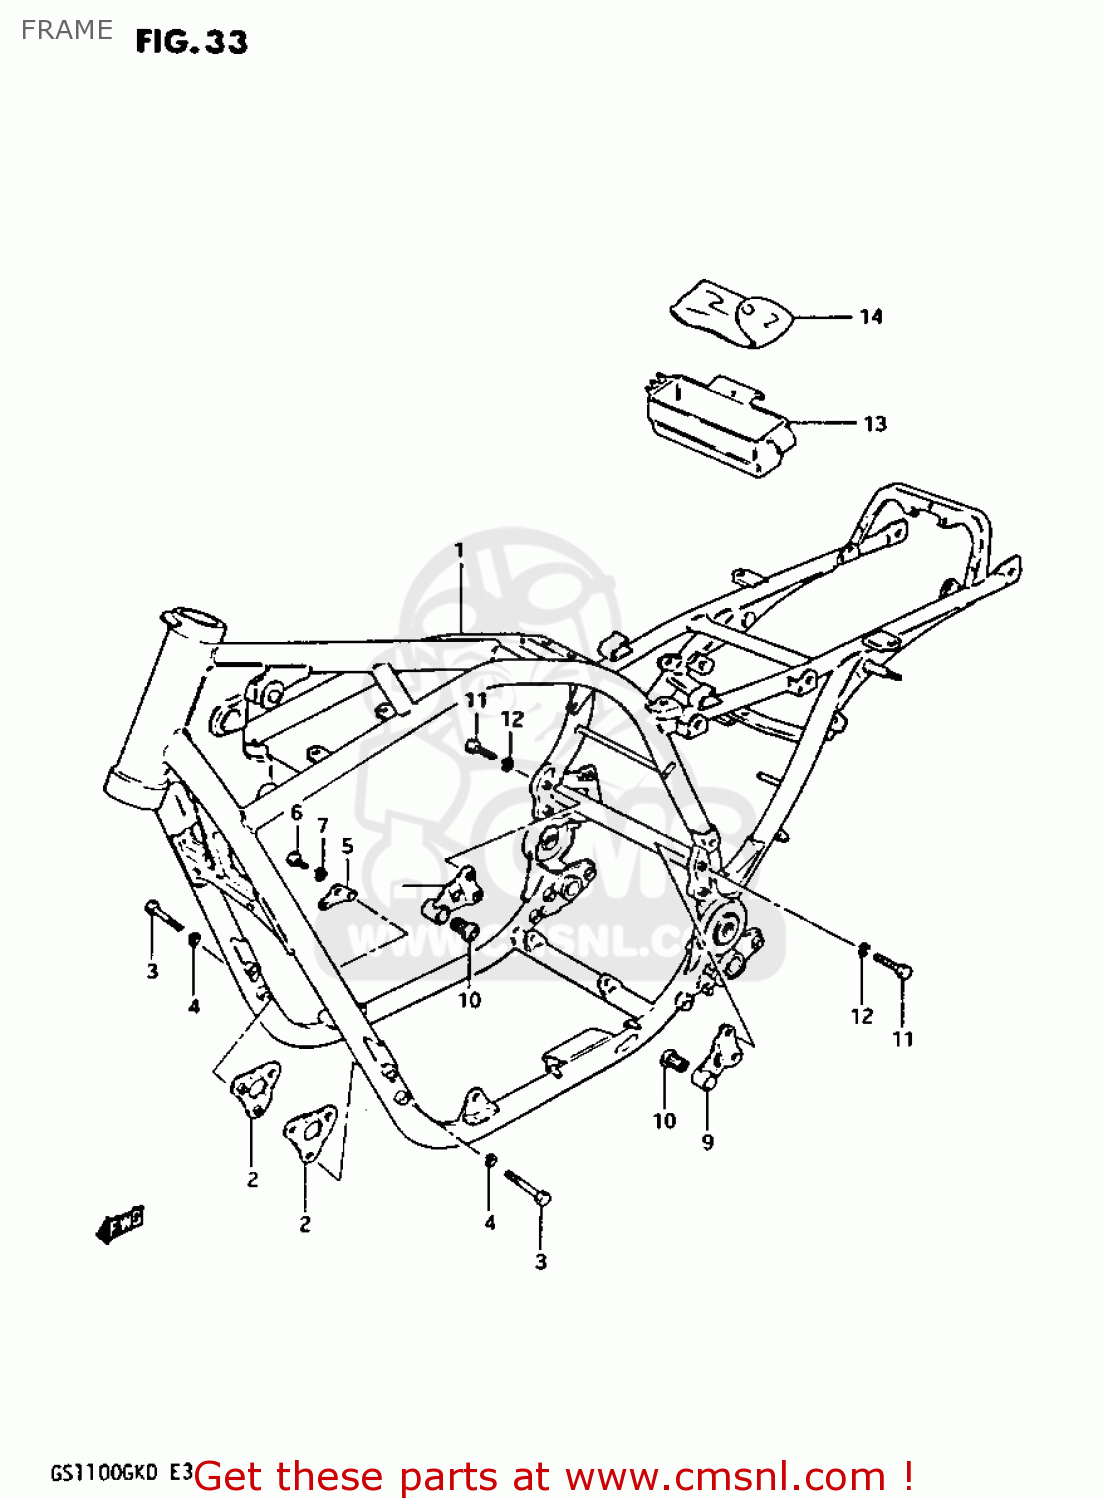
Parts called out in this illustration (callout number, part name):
1	FRAME
2	PLATE,ENGINE MOUNTING
3	BOLT
4	LOCK WASHER
5	PLATE,ENGINE MOUNTING
6	BOLT
7	LOCK WASHER
8	PLATE,ENGINE MOUNTING
9	PLATE,ENGINE MOUNTING
10	BUSHING
11	BOLT 8X40
12	LOCK WASHER
13	HOLDER,TOOL
14	TOOL SET
